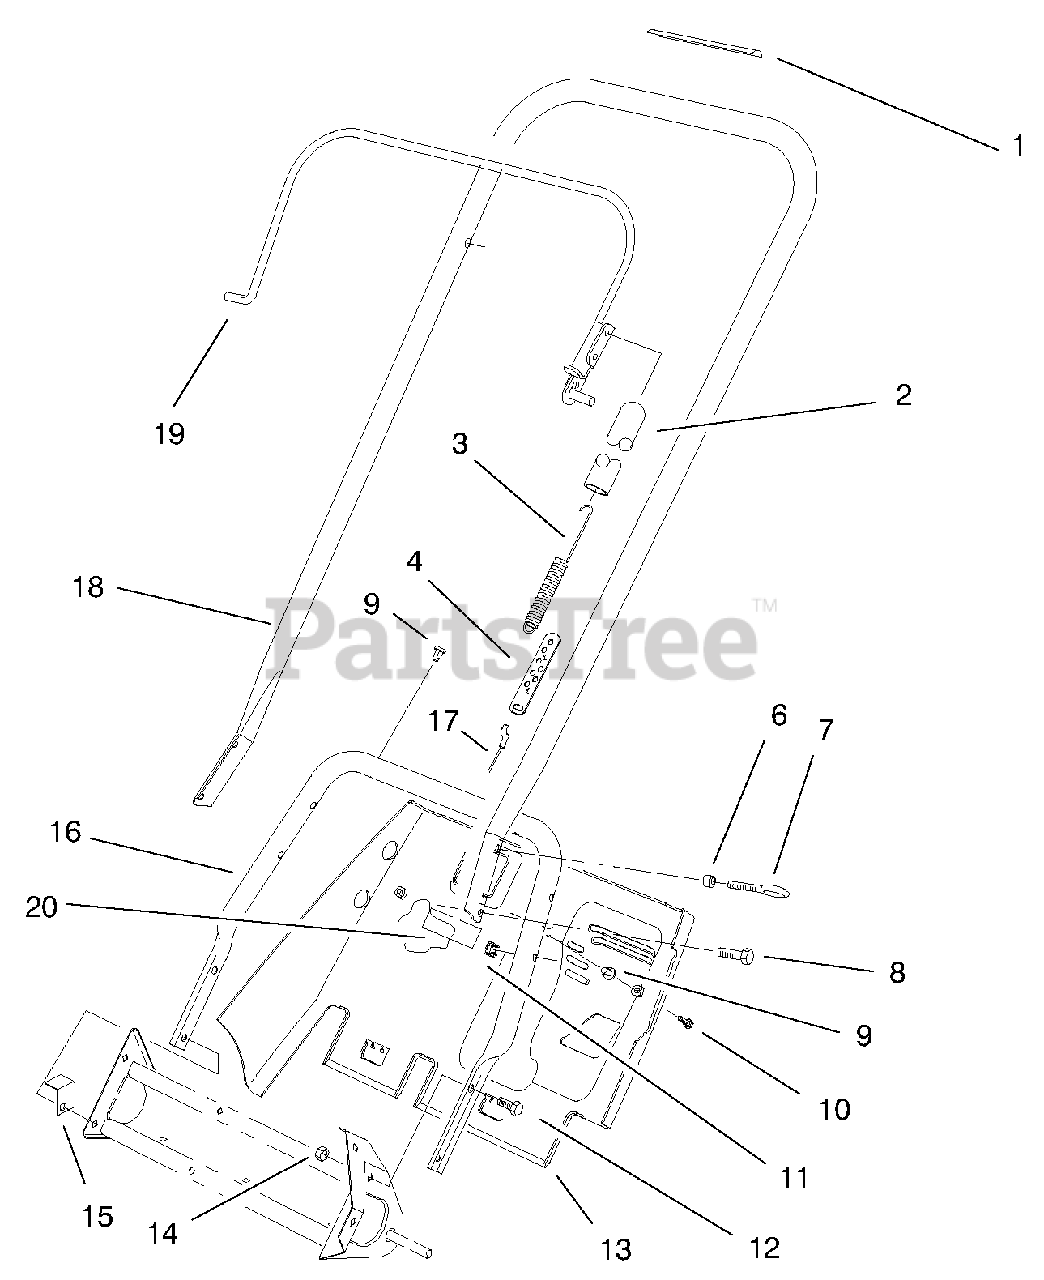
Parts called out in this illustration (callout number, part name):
1	Decal-Rotor Drive
2	Spring Cover
3	Clutch Spring
4	Clutch Cable Adjuster
6	Rotor Bld Spacer
7	Eyebolt
8	Screw-Hex Hd Slot
9	Expansion Type Fastener
10	Screw-Self TAP
11	Tinnerman Nut
12	Screw-HH
13	Lower Shroud
14	Nut-Lock Ni
15	Shroud Bracket
16	Lower Handle Tube
17	Clutch Cable
18	Handle-Upper
20	Decal (only on: 28222)
